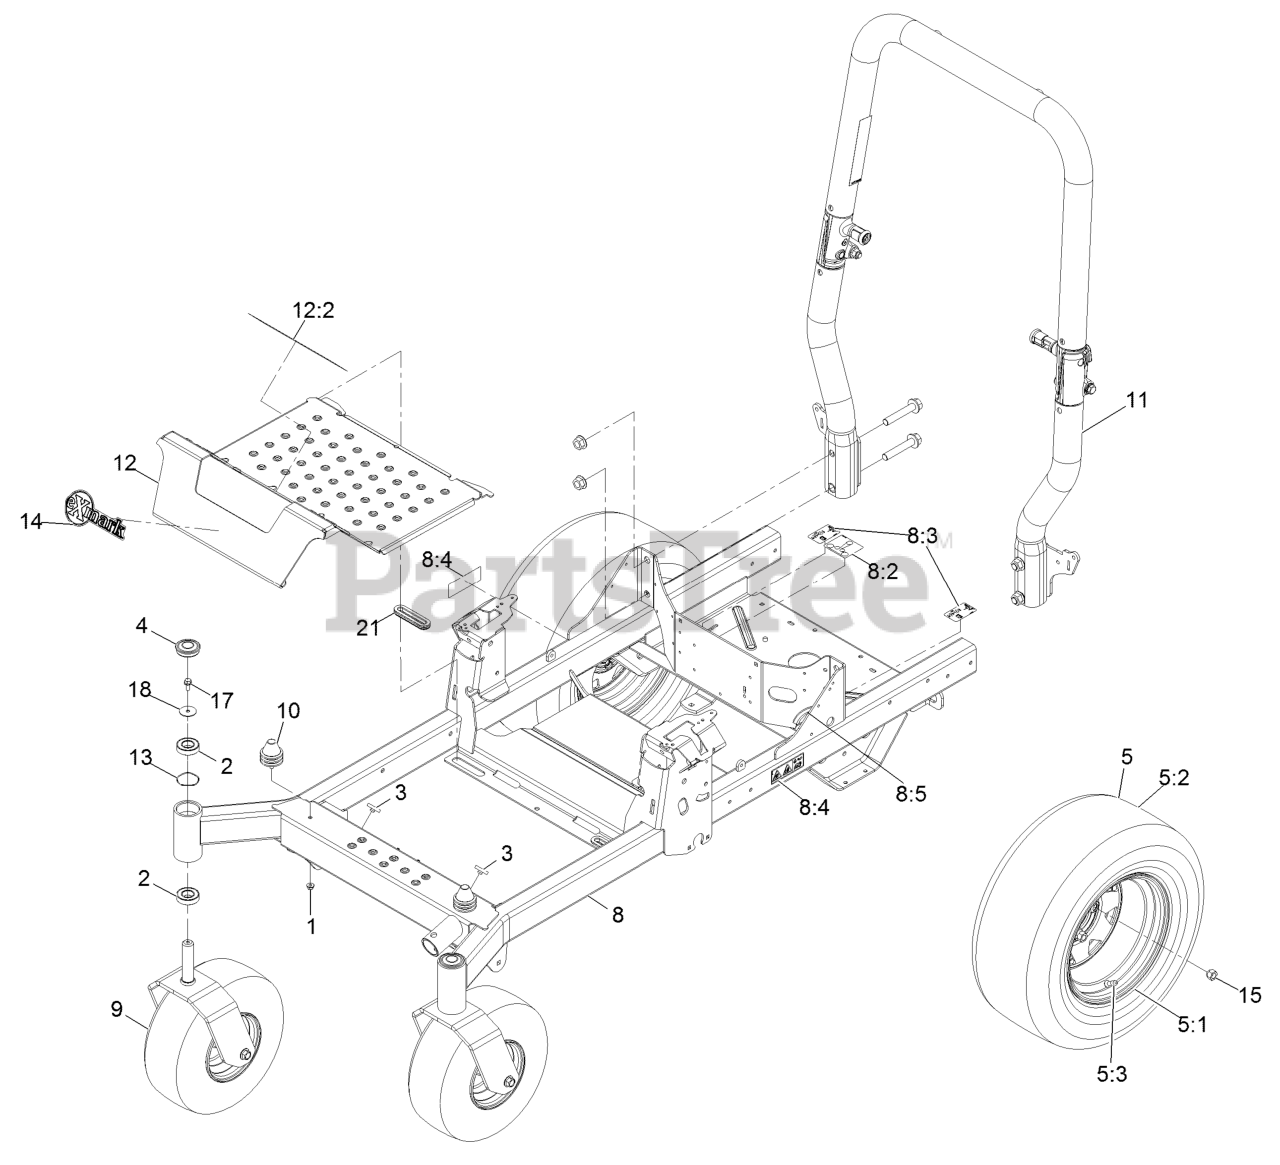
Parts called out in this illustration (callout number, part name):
1	Nut-Flange, NI
2	Bearing-Ball
3	Bumper-Push-In, Rubber
4	Cap-Grease
5	Wheel And Tire ASM
5:1	Wheel-12X7, 8 Spoke 4 On 4
5:2	Tire
5:3	Stem-Valve
8	Frame ASM
8:2	Decal-Belt Routing
8:3	Decal-Drive Release
8:4	Decal-Warning Rotating Devices
8:5	Strip-Seal
10	Isolator
11	ASM-ROPS Tapered
12	Pan Floor
12:2	Decal-Danger
14	Decal-Exmark Logo
15	Nut-Lug
17	Screw-HHF
18	Washer-Flat
21	Grommet-Rubber
